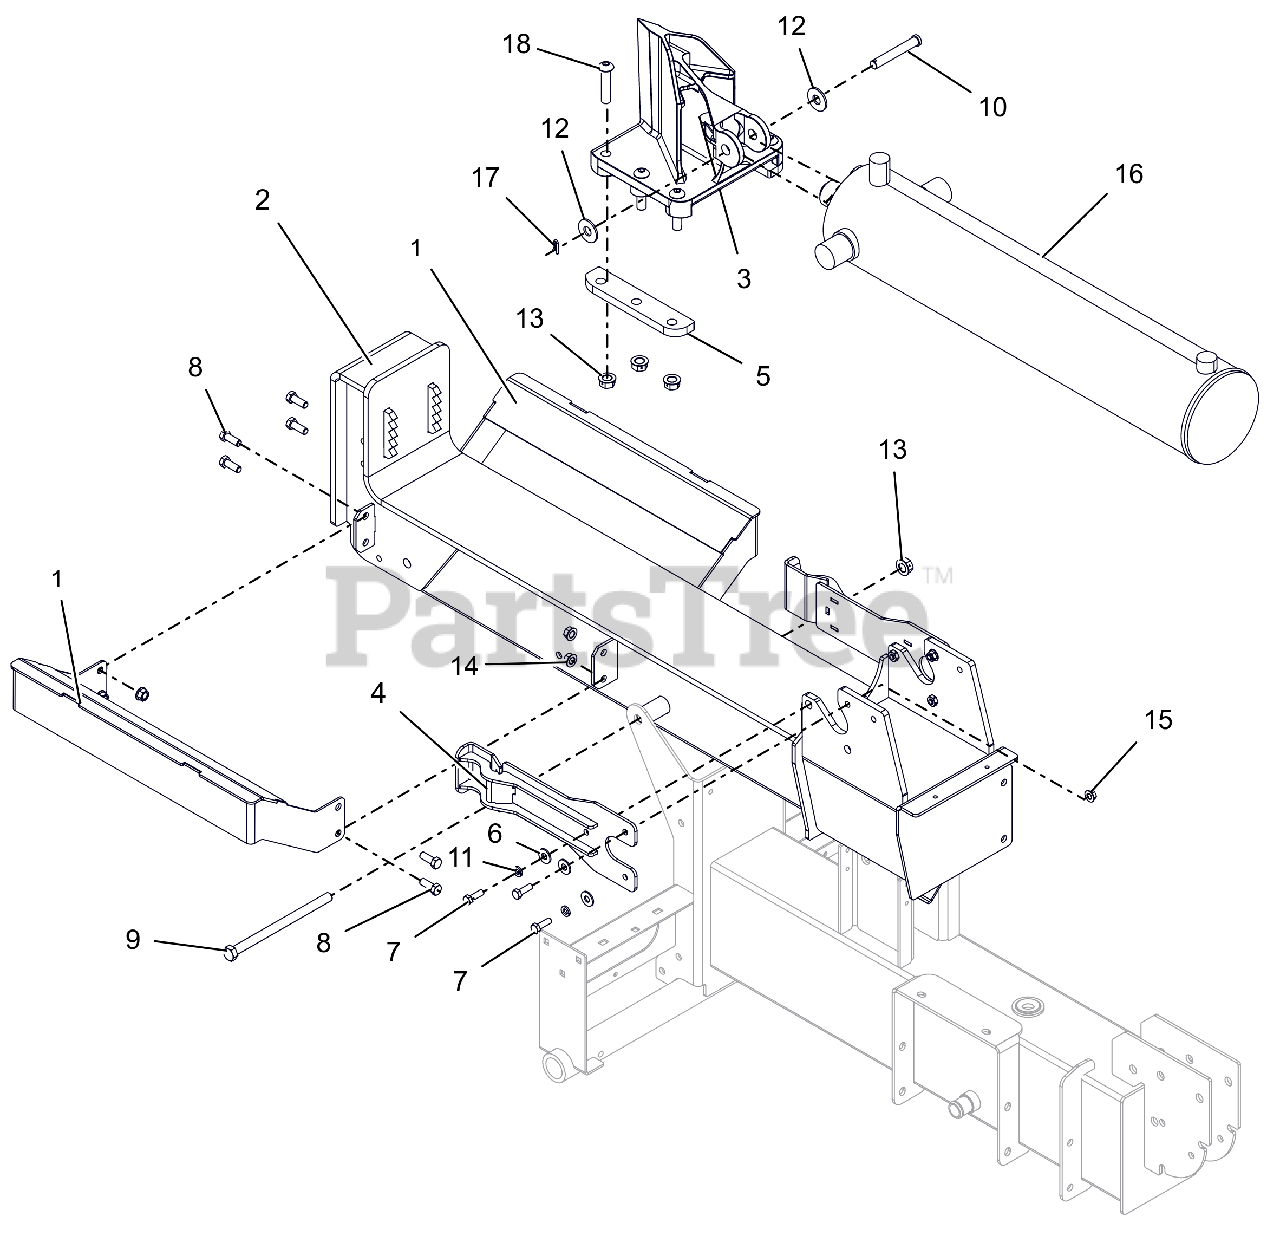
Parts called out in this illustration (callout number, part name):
1	WLDMT, CRADLE, LOG SPLITTER
2	WLDMT, BEAM - 27/34T SPLITTER
3	WEDGE-LOG SPLITTER-MACHINED
4	WLDMT, PLATE - STRIPPER
5	RETAINER-WEDGE
6	@WSHR-FL-STL.38X.875X.083 YWZC
7	@BLT-HEX .31-18X1.00 GR5 YWZC
8	@BLT-HEX .38-16X1.00 GR5 YWZC
9	@BLT-HEX .50-13X7.50 GR5 YWZC
10	PIN-CLEVIS .500 X 3.250
11	WSHR-LK .312X.097 HVY YWZC
12	@WSHR-FL-STL.563X1.38X.109YWZC
13	NUT-LK-CTR-FLG .50-13 YWZC
14	@NUT-LK-TOP-FLG .38-16 YWZC
15	@NUT-LK-TOP-FLG .31-18 YWZC
16	CYLINDER, 5' W/DECALS
17	CLIP, SPRING
18	SCR-SKH .500-13X2.250 BTH YZ
